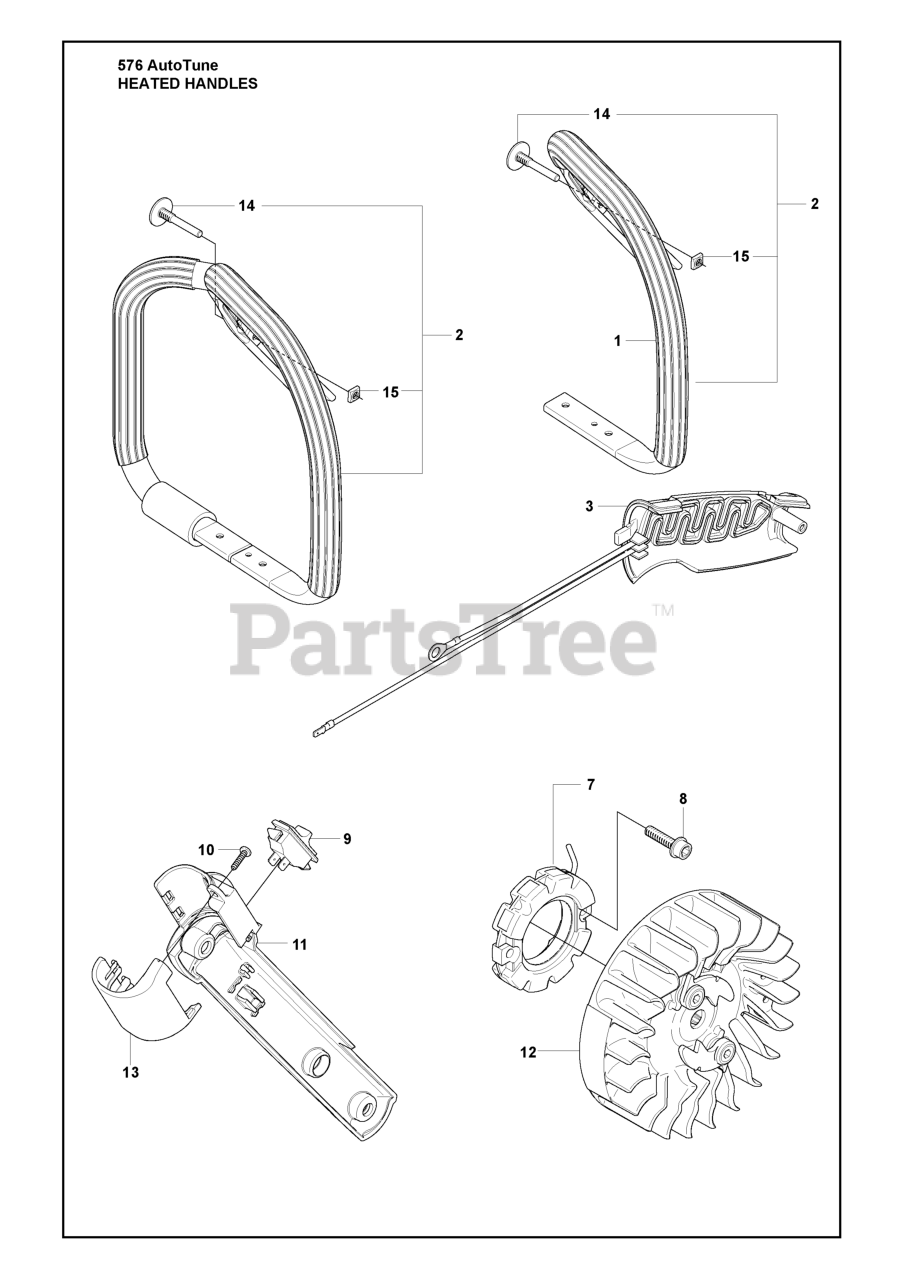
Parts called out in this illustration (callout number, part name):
1	HANDLE (G)
2	HANDLE (WAG)
7	GENERATOR STATOR
